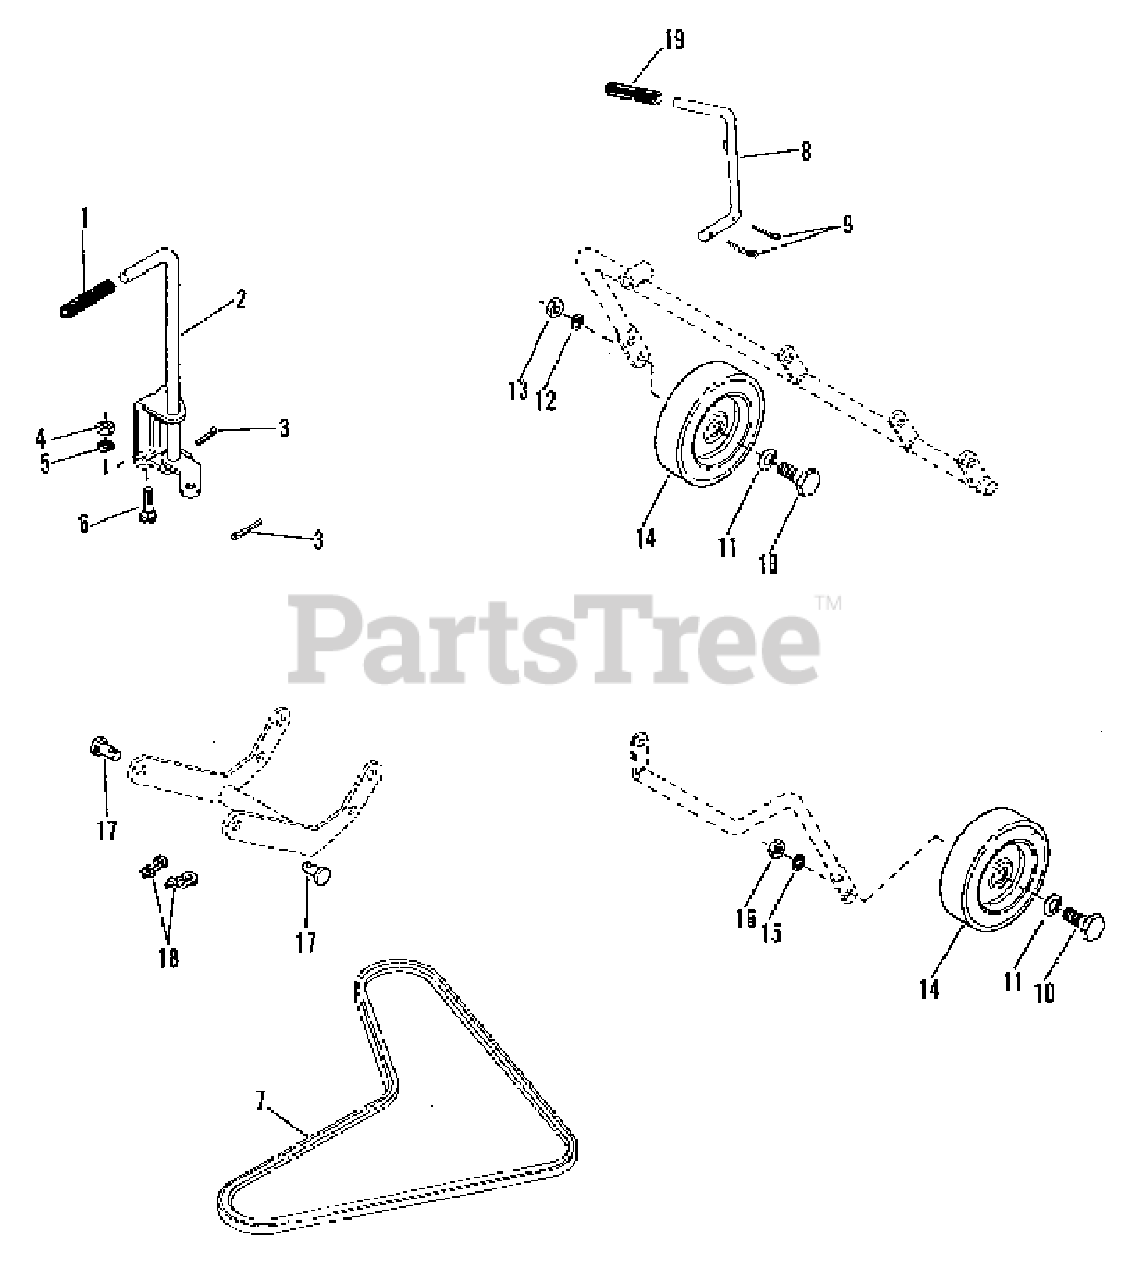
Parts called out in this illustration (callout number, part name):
1	GRIP, Handle
2	CLUTCH LEVER ASSEMBLY
3	PIN, Cotter, 3/32 x 3/4
4	NUT, Hex, 5/16-18
5	LOCKWASHER, 5/16
6	BOLT, Carriage, 5/16-18 x 3/4
7	BELT, V
8	HANDLE, Control
9	PIN, Cotter, 1/8 x 1
10	BOLT, Wheel
11	WASHER, Spring
12	WASHER, Special
13	NUT, Hex, Jam, Lock, 3/8-16
14	WHEEL & TIRE ASSEMBLY
15	LOCKWASHER, 3/8
16	NUT, Hex, 3/8-16
18	CLIP, Spring
19	GRIP, Handle 1/2 x 3/4
